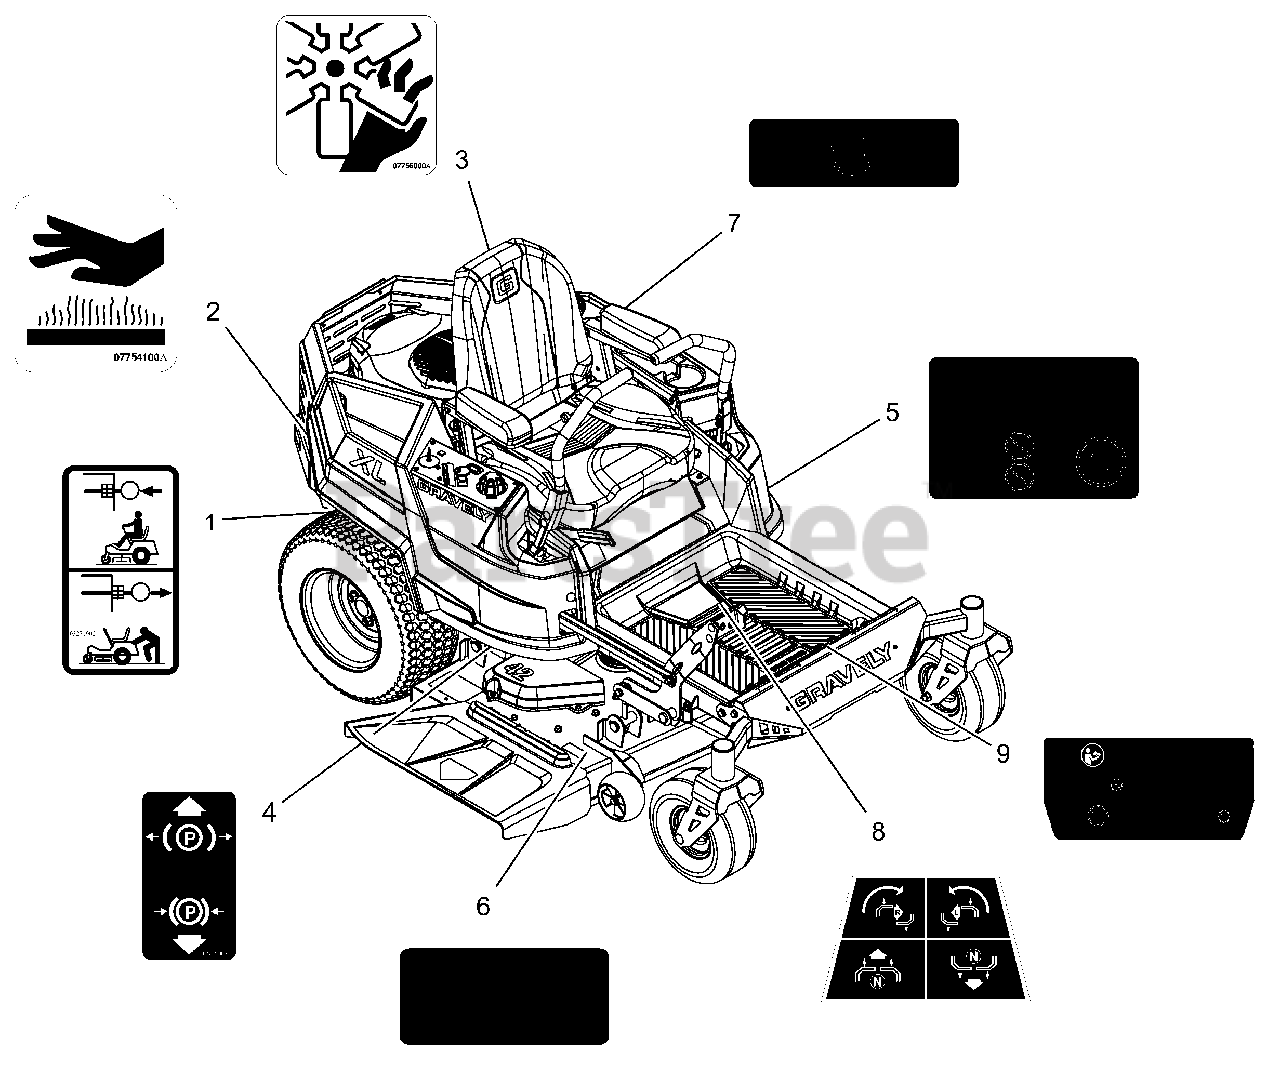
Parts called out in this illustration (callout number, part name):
1	DECAL, TRANSMISSION DISCONNECT
2	DECAL, HOT SURFACE
3	DECAL, DANGER FAN
4	DECAL, PARKING BRAKE LEVER
5	DECAL, SAFETY - MOWER DECK
6	DECAL, SAFETY - DECK GUARDING
7	DECAL-FUEL, WARNING
8	DECAL, STEERING
9	DECAL, MAIN SAFETY
